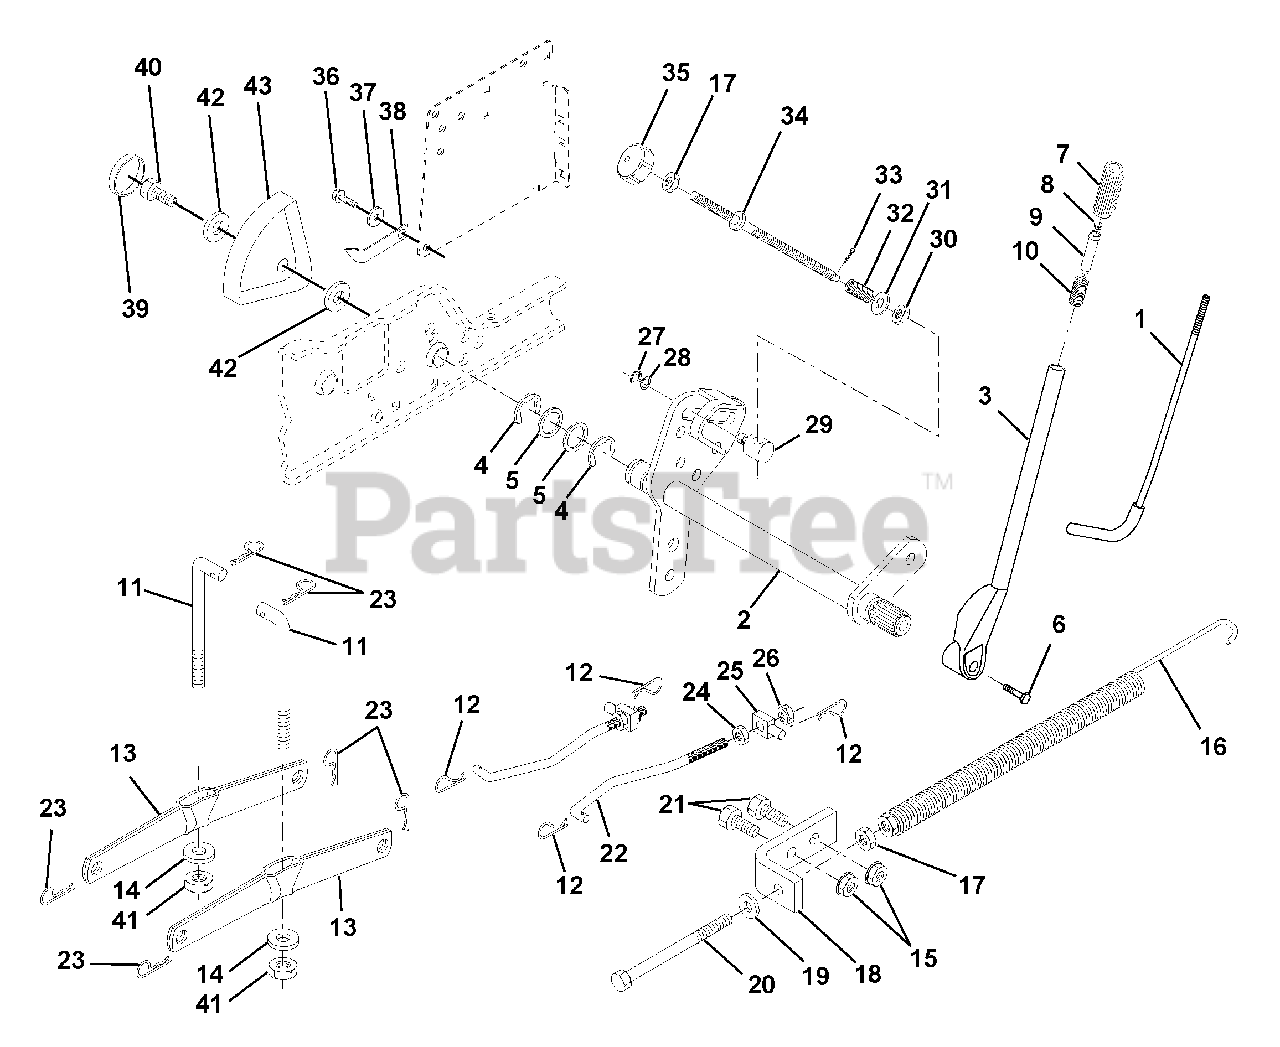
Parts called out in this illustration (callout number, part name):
1	Rod Asm., Lever
2	Shaft Asm., Lift Vgt
3	Lever Asm., Lift Rh
4	E-Ring Truarc #5133-87
5	Washer 29/32 x 1-1/4 x 16 Ga.
6	Bolt, Fin Hex 3/8-16 x 1-1/2
7	Grip, Handle Fluted
8	Button, Plunger
9	Plunger, Lever Lift
10	Spring 2-1/8"
11	Link Lift
12	Retainer, Spring
13	Arm, Suspension Vgt
14	Bearing
15	Nut, Crownlock 3/8-16 Unc
16	Spring Asm., Assist Lift
17	Nut, Hex Jam 3/8-16 Unc
18	Bracket, Spring Assist
19	Washer 13/32 x 13/16 x 16 Ga.
20	Bolt, Adjust Spring Assist
21	Bolt, Fin Hex 3/8-16 x 1
22	Link, Front
23	Retainer, Spring
24	Nut, Jam Hex 1/2-13 Unc
25	Trunnion
26	Nut, Lock W/Wsh 1/2-13 Unc
27	Ring, Klip #T5304-37
28	Washer 15/32 x 3/4 x 16 Ga.
29	Trunnion, Dp Stop Dbl Thds Plt
30	Nut, Special
31	Washer 13/32 x 5/8 x 16 Ga.
32	Spring, Compression Inf Hgt
33	Pin, Cotter 3/32 x 1/2
34	Rod, Adj Lift
35	Knob, Inf 3/8-16 Unc
36	Screw, Thdrol 3/8-16 x 3/4
37	Washer, Nylon
38	Pointer, Pnt Height Indicator
39	Plug, Hole
40	Screw Thdrol 5/16-18 x 3/4
41	Nut, Crownlock 3/8-24
42	Washer 11/32 x 1-1/2 x 10 Ga.
43	Scale, Indicator Height
